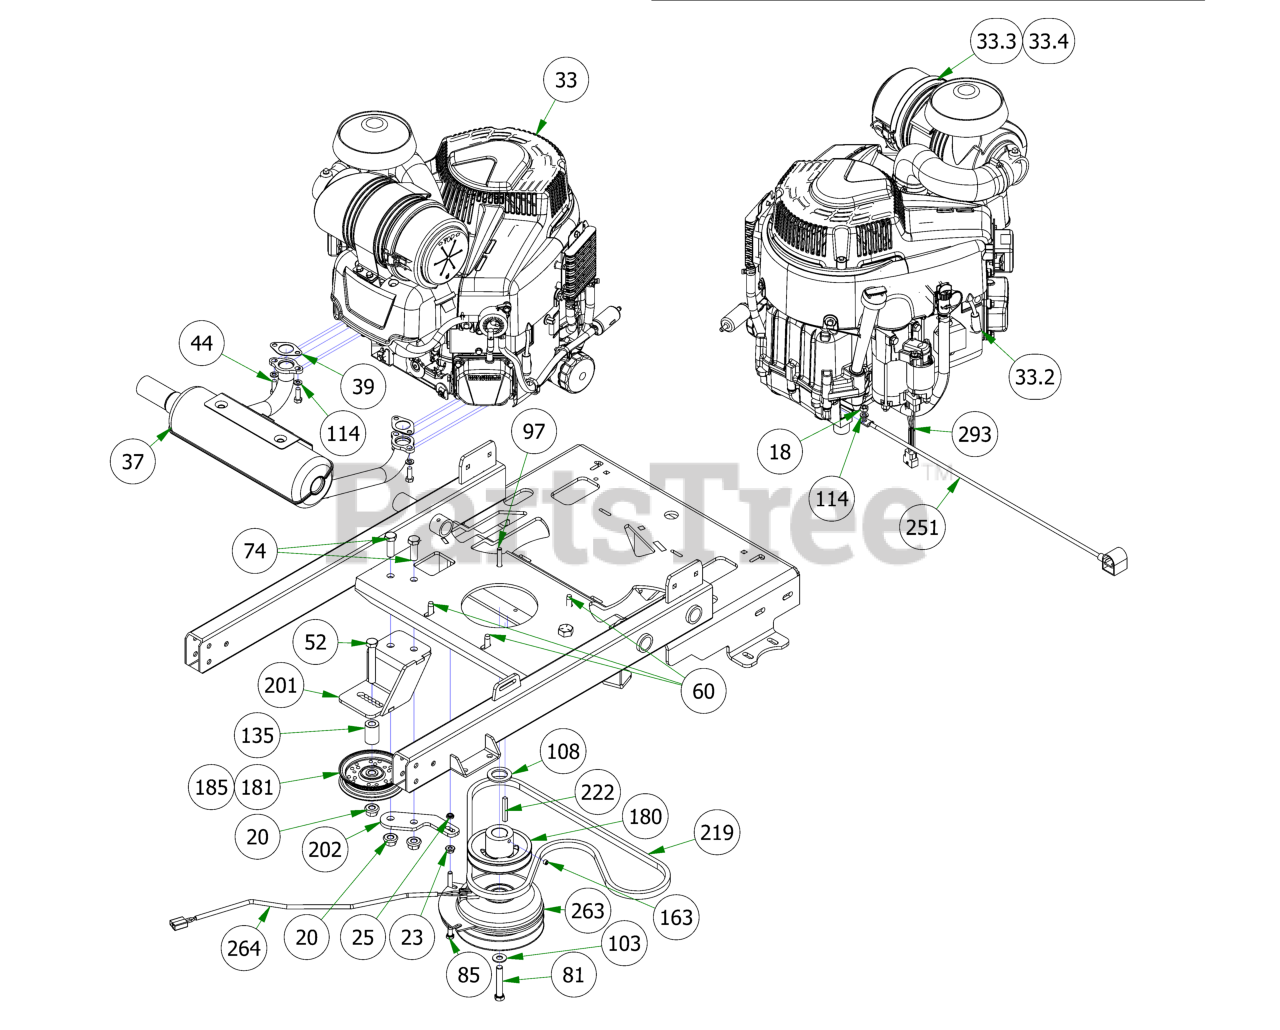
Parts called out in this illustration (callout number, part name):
18	5/16-18 HEX NUT ZINC
20	1/2-13 NYLON INSERT FLANGE LOCKNUT ZINC
23	5/16-18 HEX SERRATED FLANGE NUT HARD/ZINC
25	5/16-18 NYLON INSERT JAM LOCKNUT ZINC
33	28HP Briggs Vanguard 810cc
33.2	Spark Plug
33.3	Canister Air Filter- Outer
33.4	Canister Air Filter- Inner
37	Briggs 28 EFI Exhaust Revolt
39	Exhaust Gasket
44	Torx Bolt-Exhaust
52	1/2-13 X 3-1/4 HEX CAP SCREW (GR.5) ZINC
60	3/8-16 X 1-1/8HEX WASHER UNSLOT SERRATED (TRI-LOB) TRS
74	1/2-13 X 1-1/2 HEX CAP SCREW (GR.5) ZINC
81	7/16-20 X 2-1/2 HEX CAP SCREW (GR.8) ZINC YELLOW
85	5/16-18 X 5-1/2 HEX CAP SCREW (GR.5) ZINC
97	5/16-18 X 1-3/4 HEX CAP SCREW (GR.5) ZINC
103	3/8 FLAT WASHER USS (1" OD) ZINC
108	1.140 ID X 1.750 OD X .132 THICK FLAT WASHER PLAIN
114	5/16 SPLIT LOCKWASHER ZINC
135	.502 ID X .750 OD X 1.500 Long Spacer
163	5/16-24 X 1/4 SOCKET SET SCREW (CUP PT) PLAIN
180	4 3/4 Motor Pulley
181	4 3/4 Idler Pulley - ABFI-76
185	5-3/4 Idler Pulley
201	Idler Pulley Bracket Weldment 2019 Stand On
202	2019 Stand On Clutch Stop Bracket
219	2019 Stand On Pump Belt (Timken# 47-2827)
222	1/4 X 2 SQ MACHINERY KEY 1018 STL PLAIN
251	24 inch Black Cable – MZ/ZT
263	Clutch Assembly
264	Clutch Pigtail
265	2019 Stand On Frame
293	2021 28 Briggs EFI Pigtail
